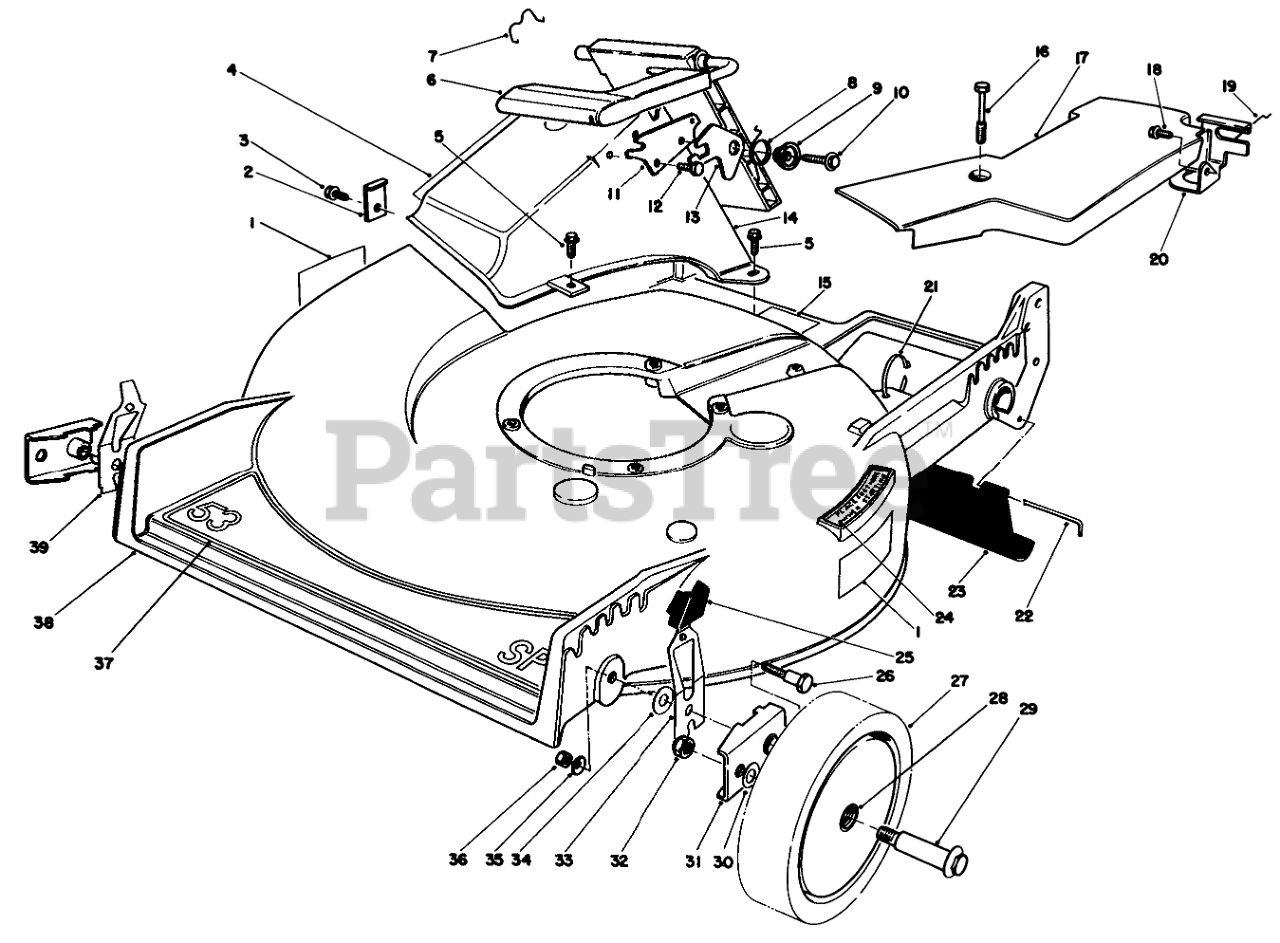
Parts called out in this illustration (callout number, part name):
1	Decal Danger
2	TUNNEL CLIP
3	SCREW
4	DECAL - DANGER
5	SCREW-HWH
6	Discharge Door Assembly
7	DOOR RET SPRING
8	TORSION SPRING
9	DOOR SPACER
10	SCREW-HWH
11	DOOR LATCH PLATE
12	SCREW-PLASTITE
13	SAFETY LATCH
14	Tunnel Discharge
15	Decal
16	SCREW-HHFTF
17	Belt Cover
18	SCREW-HWHTF
19	RETAINER-CABLE
20	Bracket-Traction Adj.
21	TIE-CABLE
22	ROD-SHIELD
23	SHIELD-TRAILING
24	DECAL - STEP PAD INT'L
25	KNOB-ARM
26	PIVOT SCREW
27	Wheel & Tire Assembly (Incl. Ref. #28)
28	BUSHING
29	BOLT-WHEEL
30	WASHER
31	HP PIVOT ARM ASM
32	Nut
33	L. HP SPRING ARM ASM
34	WASHER-PIVOT
35	WASHER-BELLEVILLE
36	NUT-LOCK, NI
37	DECAL - 53 SP DECK
38	21" Housing (Incl. Ref. #1)
39	R HP SPRING ARM ASM
